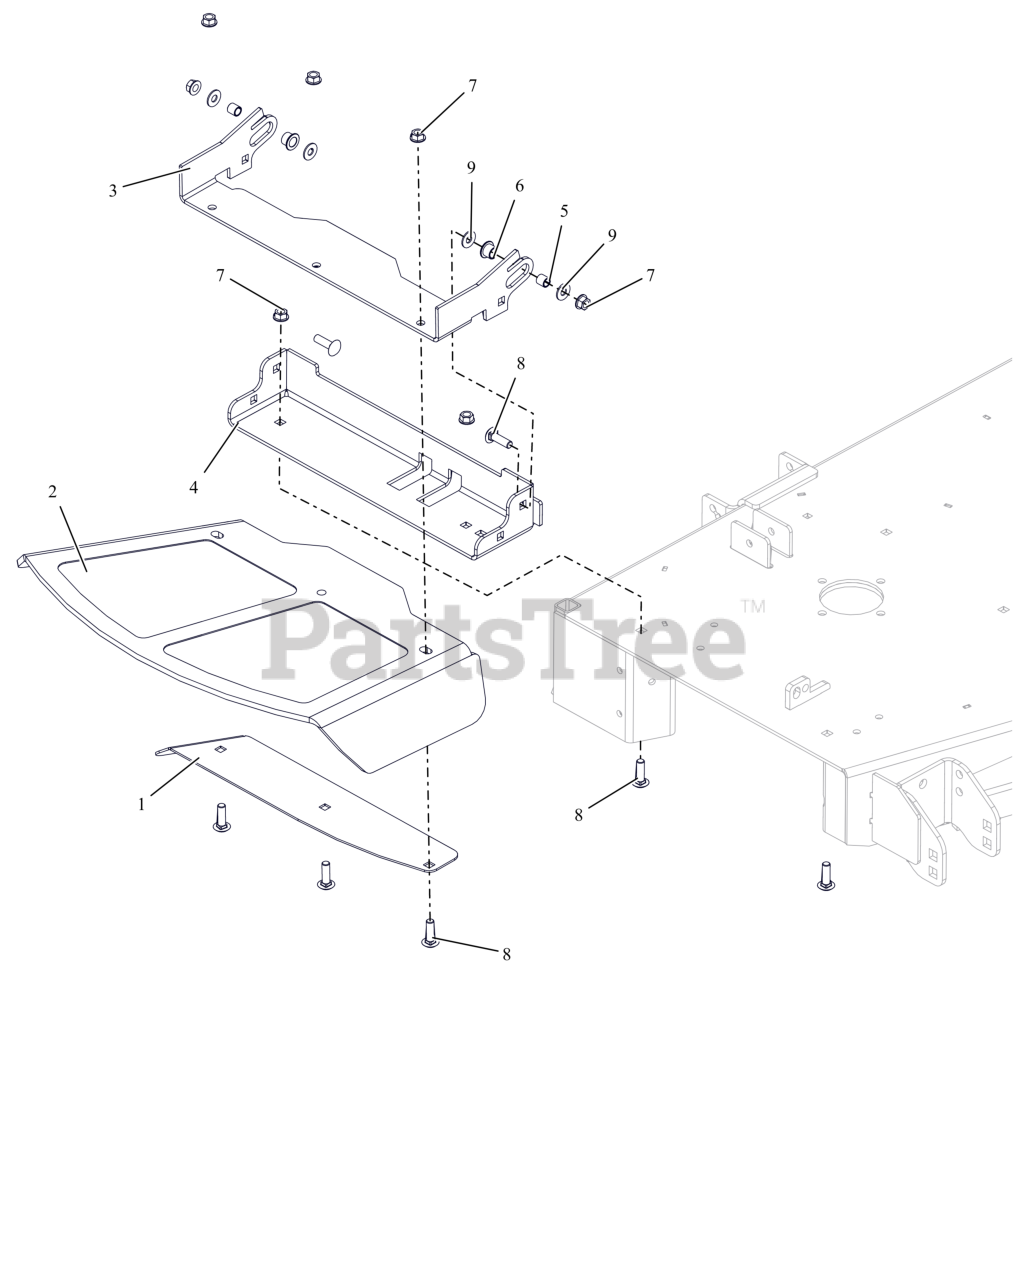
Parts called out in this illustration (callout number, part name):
1	48-60 DISCH CHUTE CLMP PLT-RED
2	CHUTE, FORMED RUBBER DISCHARGE
3	BRKT, CHUTE MOUNT (RED)
4	BASE, DISCHARGE CHUTE MTG BRKT (RED)
5	SPCR, .385X.500X.350
6	BSHG, FLANGED .50X.625X.50X.062
7	NUT-LK-CTR-FLG .375-16 GF ZCC
8	BLT,RHSSN .38-16X1.25 G5 ZCC
9	WSHR, HDND 0.375X0.875X0.064 ZCC
